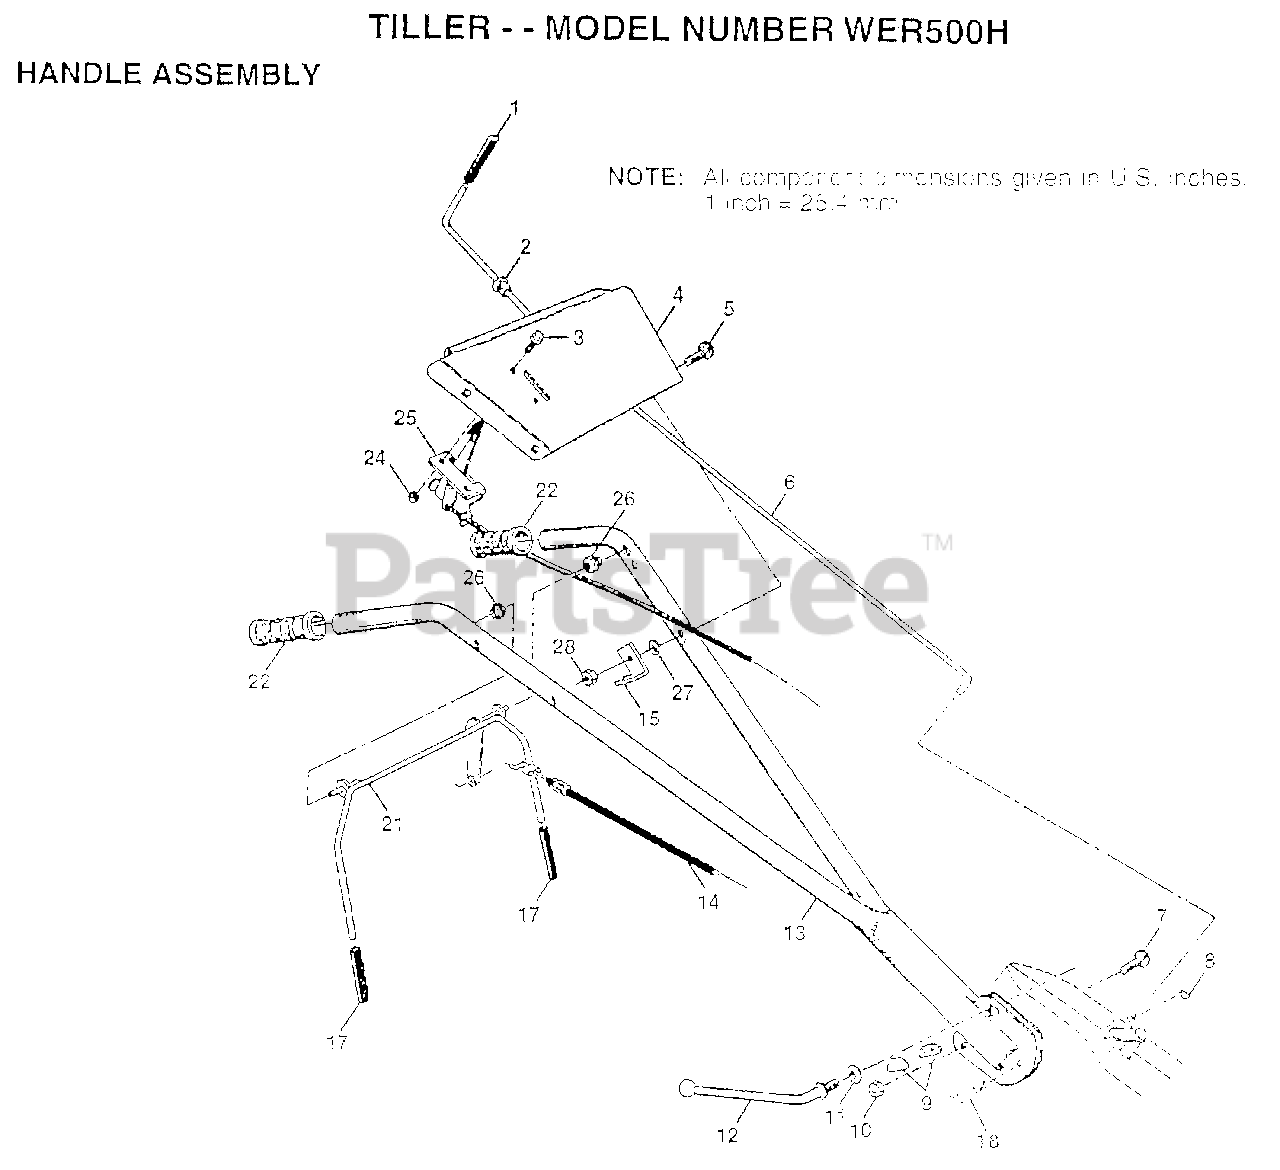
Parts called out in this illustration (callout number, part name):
1	GRIP TI
2	BUSHING
3	SCREW.PNHD.10-24
4	BRACKET.HDLE.TILL
5	BOLT CARRIAGE CRT
6	ROD SHIFT CRT
7	BOLT D
8	RETAINER M
9	LOCK CRT
10	LOCKNUT
11	WASHER CRT
12	LEVER LOCK CRT
14	CABLE.CLUTCH.Z-BE
15	BRACKET.CLUTCH.CA
17	GRIP BAR CRT
18	BOLT PIVOT
21	BAR.ASM.CNTRL.VPL
22	"GRIP,HANDLE"
25	"CONT,THROTTLE"
26	GROMMET.HANDLE.V-
27	LOCKWASHER
28	NUT
